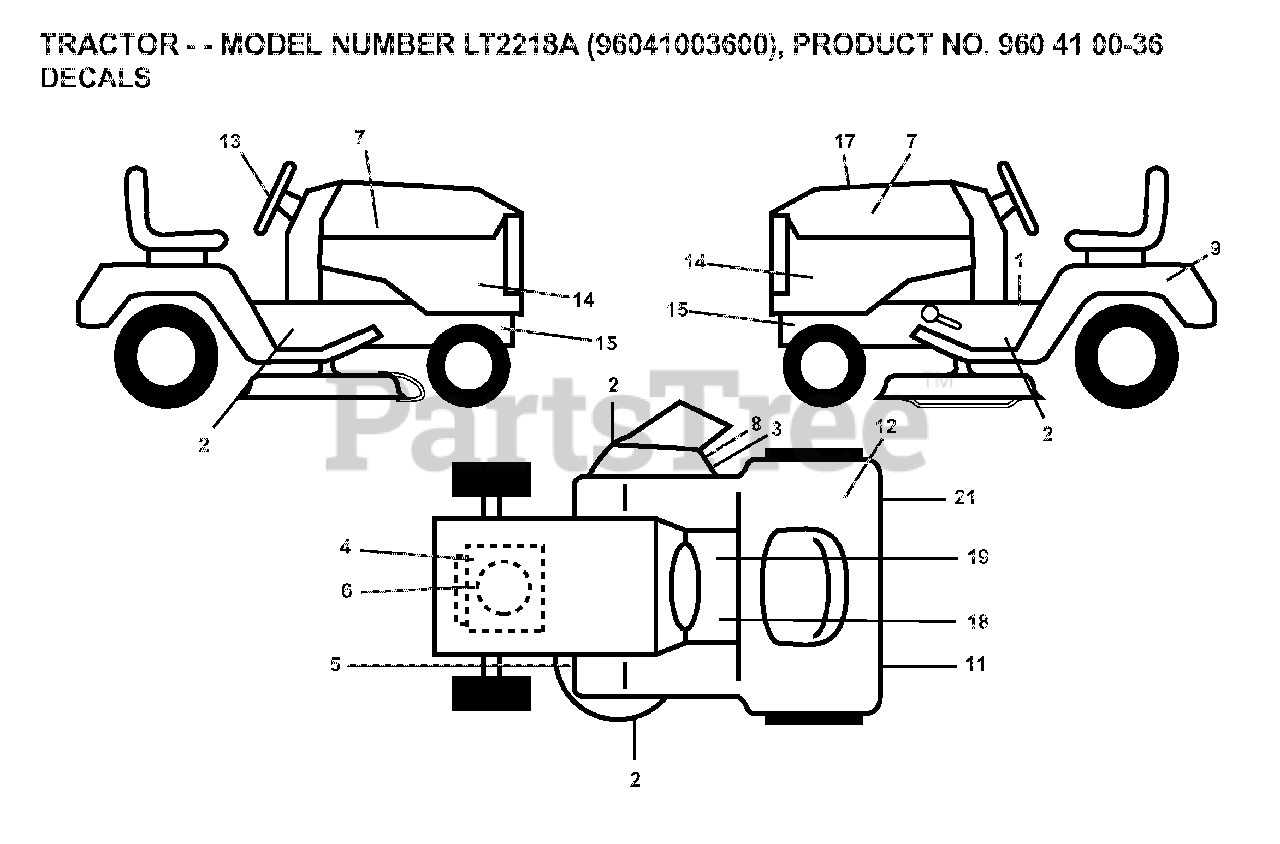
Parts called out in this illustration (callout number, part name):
3	DECAL, DEFLECT WARNING
5	DECAL V BELT SCHEMATIC
8	DECAL.INTERNATIONL.CUTFINGER
9	DECAL BTRY SYMBOLS
19	DECAL PARK BRAKE
